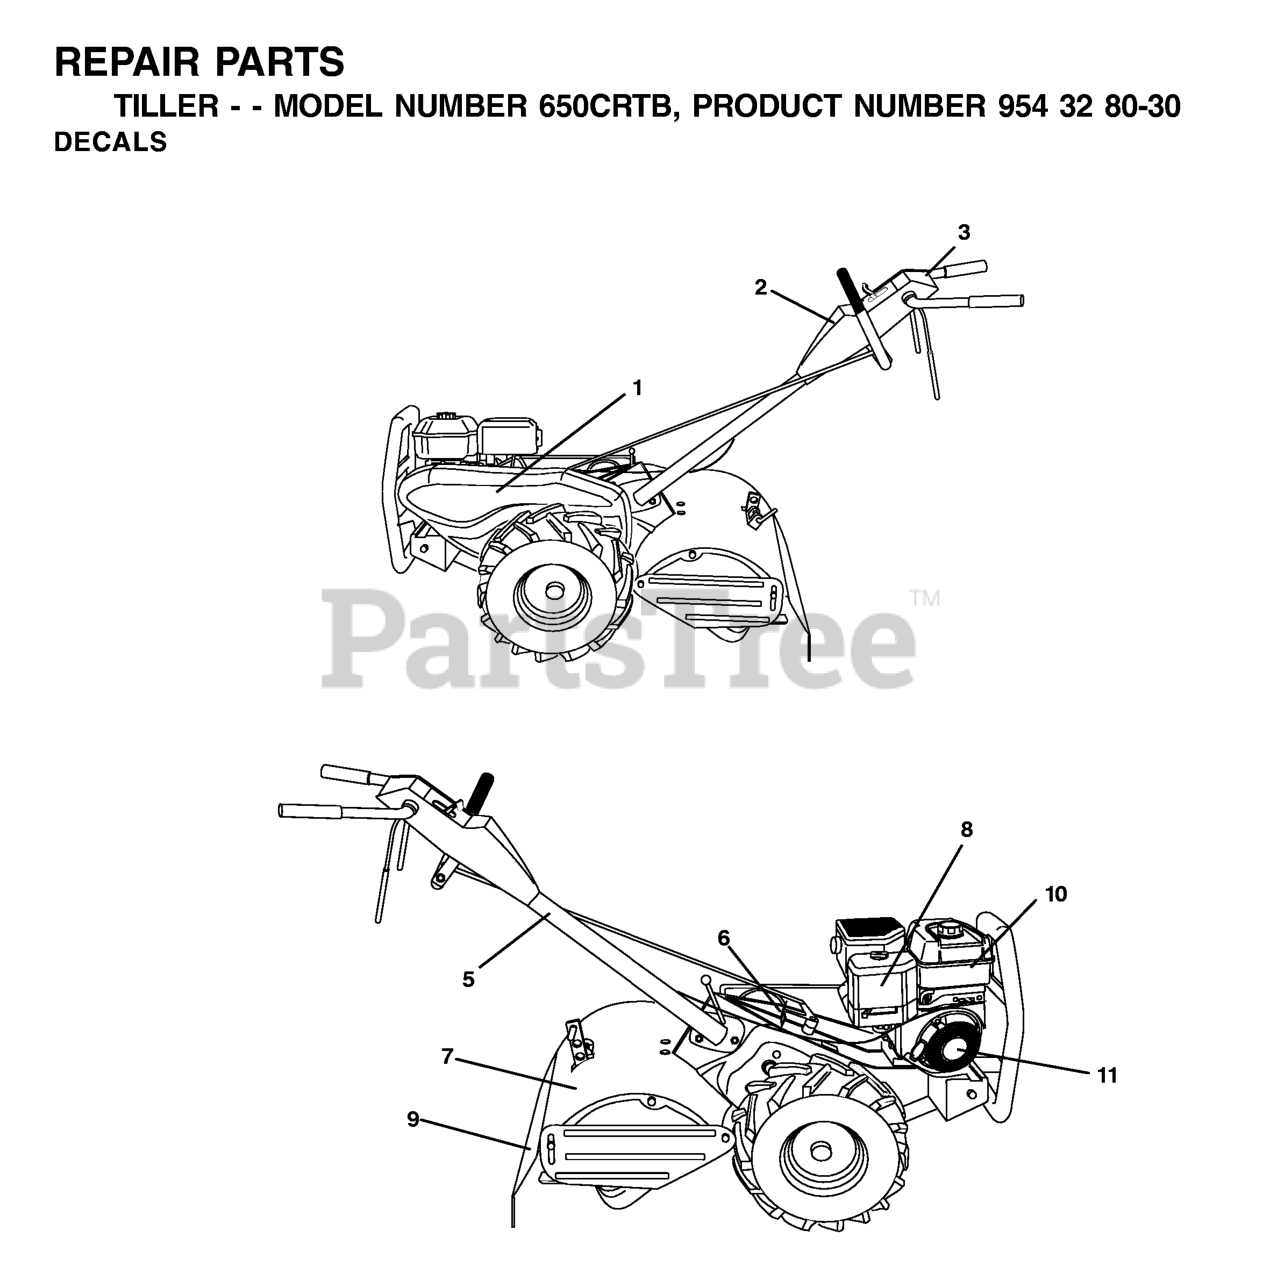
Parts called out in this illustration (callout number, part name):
1	DECAL, BOLT GUARD
2	DECAL, CTRL PANEL
3	DECAL, 650CRT
5	DECAL TI (2 2)
6	DECAL.SHIFT.INDICATOR.TILLER
7	DECAL -CAUTION
8	DECAL, ENG. B&S 6.5HP
9	DECAL TI
10	DECAL, ENG. INTEK
11	DECAL.REWIND
